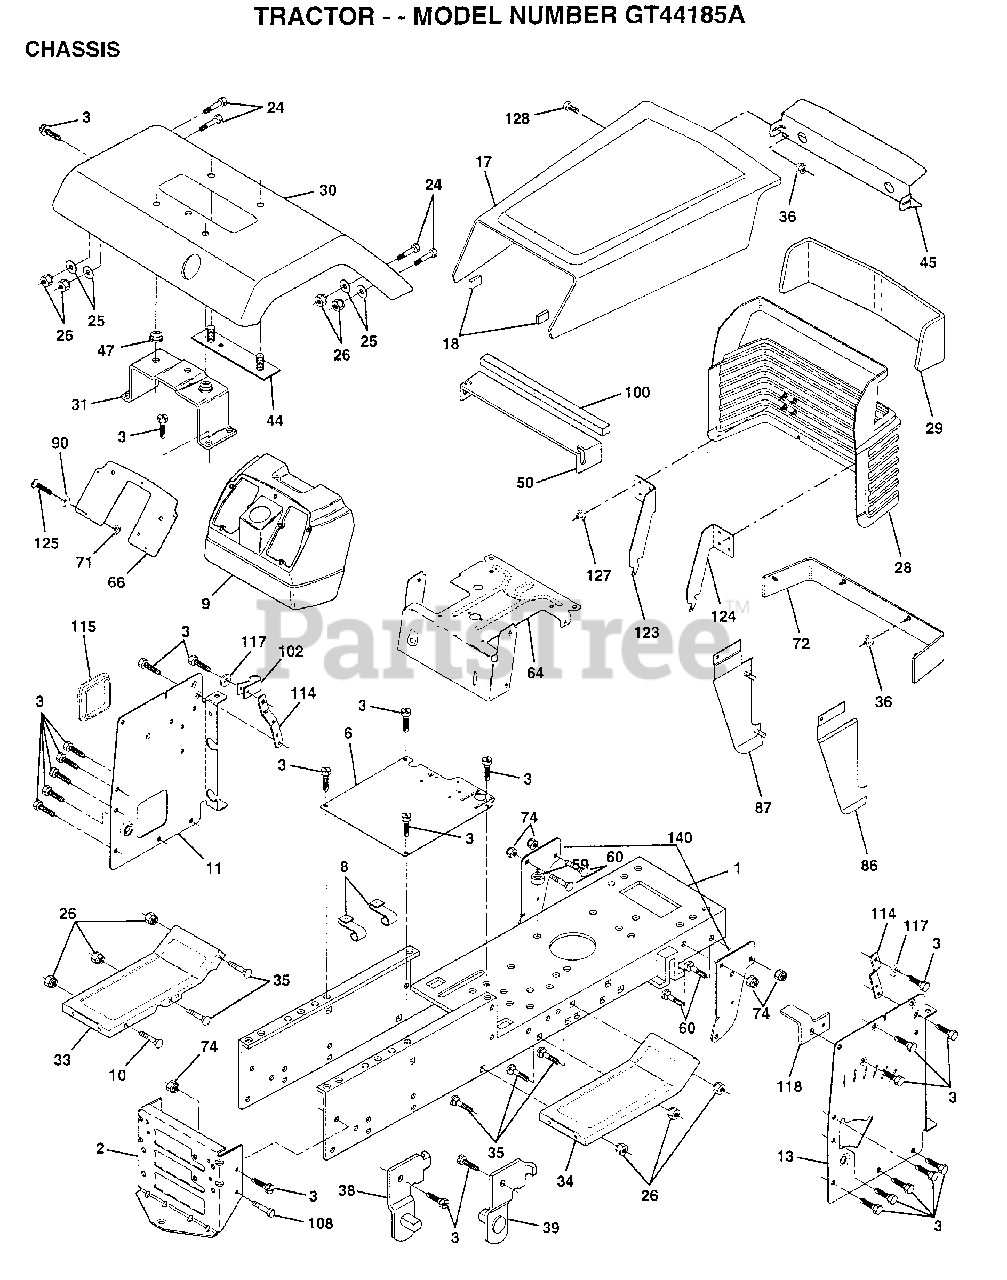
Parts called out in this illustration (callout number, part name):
1	CHASSIS WLDMT 11G
3	SCREW
8	"CLIP,INSULATOR"
9	DASH.PLASTIC.BLK
11	PANEL.DASH.LH.PNT
13	PANEL.DASH.RH.PNT
17	HOOD/GRILLE ASM
24	BOLT
25	WASHER
26	NUT
28	GRILLE ASM WELD
30	FENDER PNT
31	BRKT.ASM.FENDER
33	FOOTREST.LH.LT/GT
34	FOOTREST.RH.LT/GT
35	BOLT
36	PAL NUT LT
38	BRACKET ASM LH
39	BRACKET ASM RH
44	STRAP ASM FENDER
47	NUT-PUSH YT
50	"BAFFLE,HOOD"
60	BOLT
64	DASH.LOWER.LT
65	BOLT
66	PLATE DASH SILKSC
71	NUT HXKEP 1/4X20
72	STRAP FENDER ASM
86	PANEL SIDE RH ASM
87	PANEL SIDE LH ASM
90	WASHER PM
100	FOAM STRIP T
102	CLIP T
114	BRACKET.SUPT.DASH
115	COVER ACCESS
117	WASHER.SERRATED.
118	BRACKET.CLUTCH.MC
123	BRACKET.PICK.RH.
124	BRACKET.PICK.LH.
125	SCREW
127	PAL NUT
128	SCREW SPECIAL
